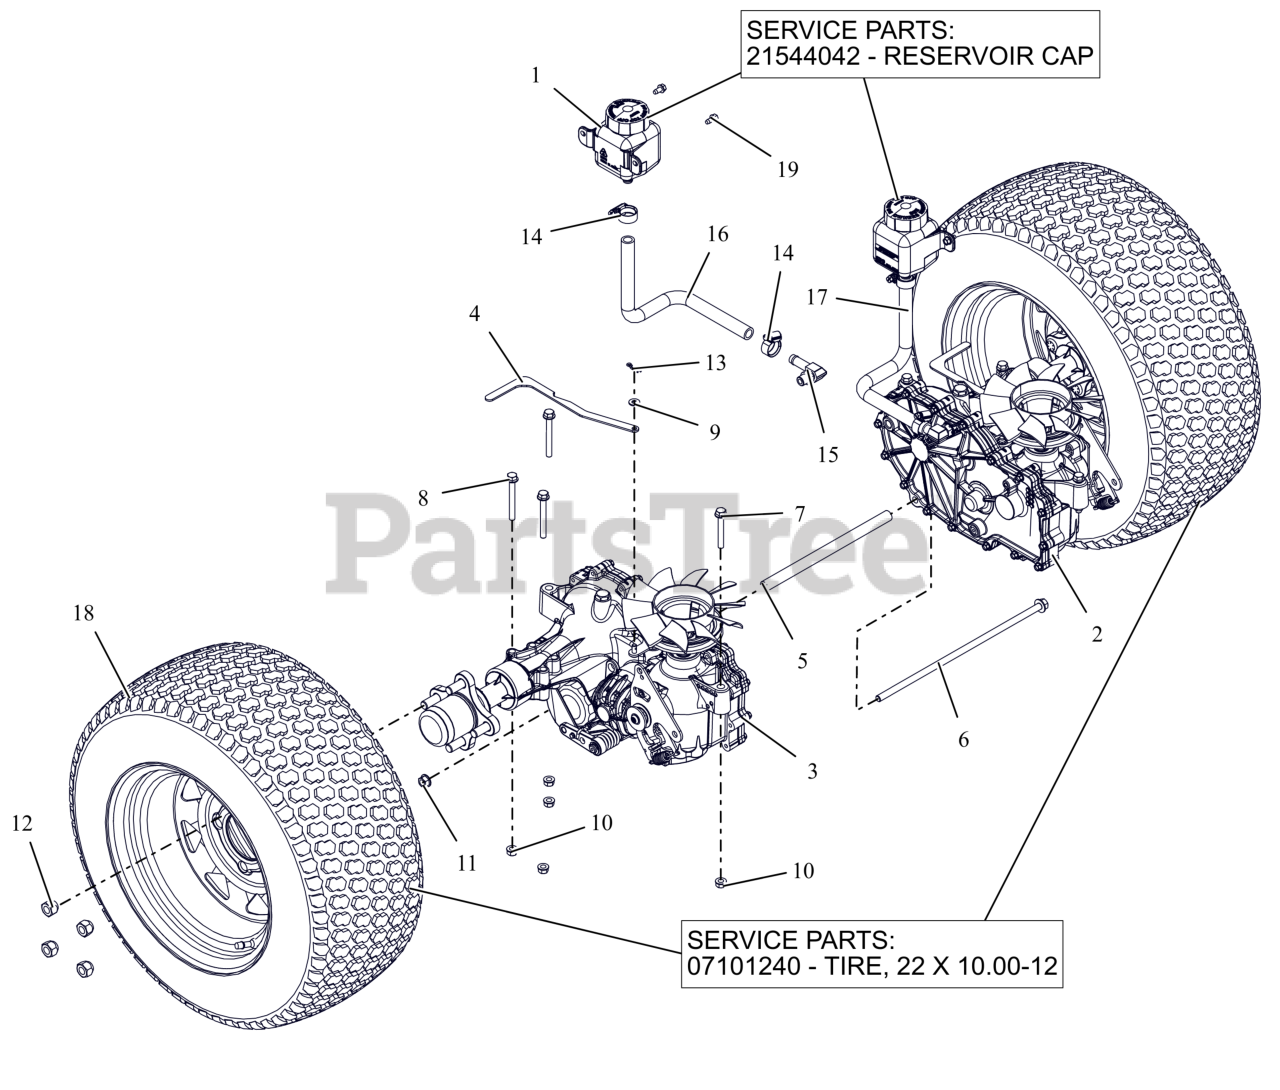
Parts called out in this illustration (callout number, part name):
1	TANK, EXPANSION
1	CAP, HYDRO RESERVOIR REPLAC.
2	TRANSAXLE, ZT3100 LH
3	TRANSAXLE, ZT3100 RH
4	BRKT, VALVE DUMP
5	SPCR,TRANS. .406IDX.63ODX9.95L
6	BLT,HEX-FLG .38-16X13 G5 ZCC
7	BLT,HEX-FLG .31-18X2.25 G5 ZCC
8	BLT,HEX-FLG .31-18X2.75 G5 ZCC
9	WSHR,FLT .281X.625X.065 ZCC
10	NUT,LK-CTR-FLG .31-18 GF ZCC
11	NUT-LK-CTR-FLG .375-16 GF ZCC
12	NUT, WHEEL .50-20 ZCC
13	PIN, HAIR #225 .072X1.09
14	CLAMP,.88 DIA. HOSE
15	FITTING, HYD (90 DEG)
16	HOSE, FORMED EXPANSION -HD RH
17	HOSE, FORMED EXPANSION -HD LH
18	ASM, WHL/TIRE 22X10.00-12 K500
18	TIRE, 22X10.00-12
19	SCR-TAP .25-20X.50 HWH ZCC
